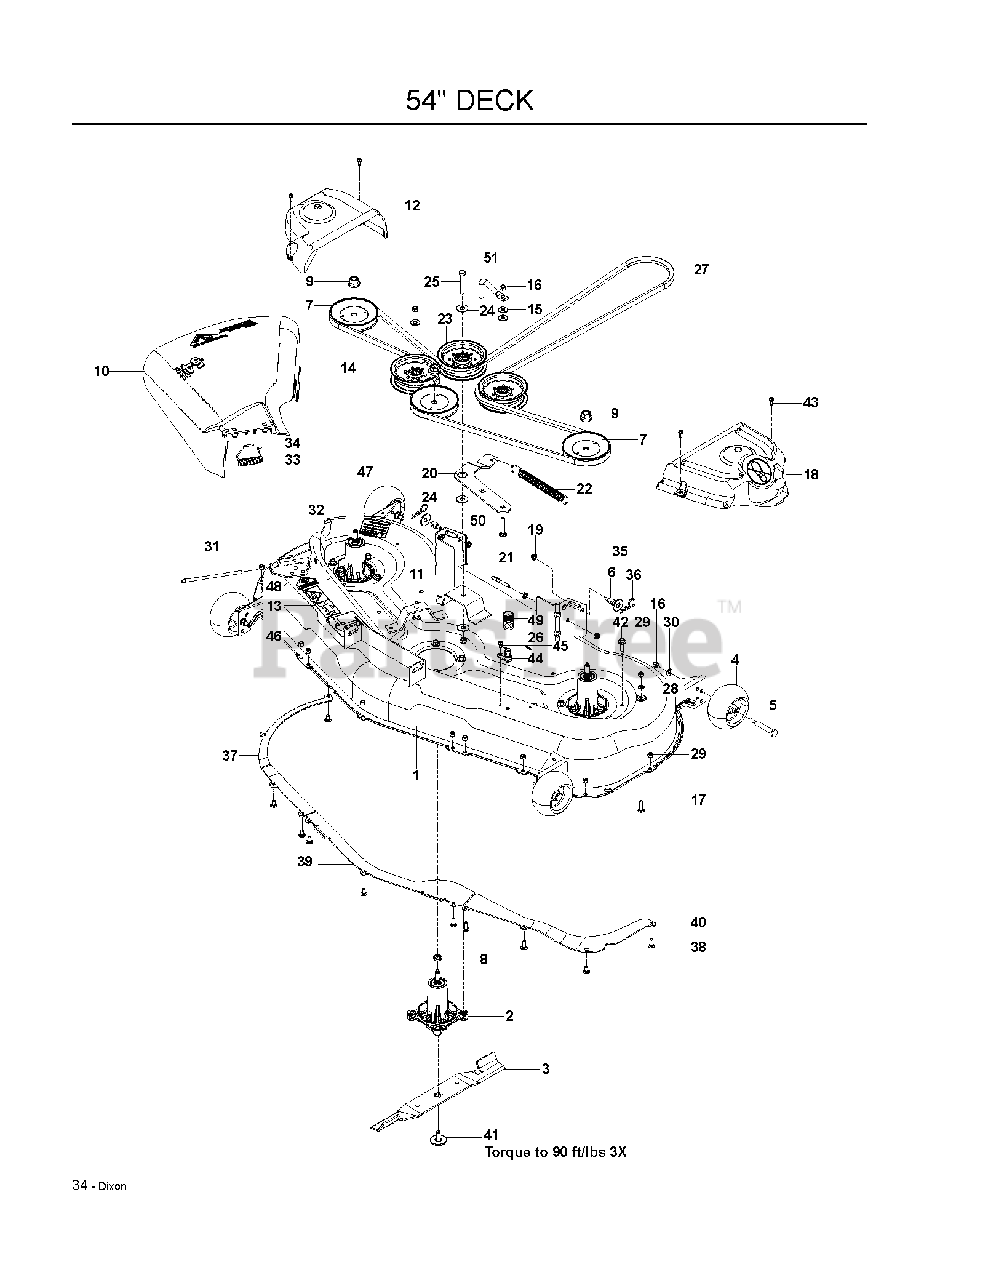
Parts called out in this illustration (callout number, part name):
1	DECK.STAMPED.54".W/DECALS.BLUE
2	MANDREL GREASABLE
3	BLADE, BAGGING 54"
4	GAUGE WHEEL
5	SHOULDER BOLT 1/2X2-5/8 ZD SPE
6	STUD.FASTNER.W/ANTI-ROTATE
7	PULLEY
9	LOCKNUT - 9/16
10	DEFLECTOR, 54"
11	RHSNB 3/8C X 2
12	BELT SHIELD, RT
13	DECAL, EURO SEVERING
14	PULLEY.IDLER.2006
15	WASHER 3/8 FLAT
16	NUT 3/8-16 NYLOC
17	BOLT 5/16C X 3/4" CARRIAGE
18	BELT SHIELD, LT
19	5/16-18 NYLOC FLANGE NUT
20	ARM.IDLER.BLACK
21	EYEBOLT, RH
22	SPRING, DECK BELT
23	PULLEY.IDLER.MWR.STATIONARY.LH
24	WASHER 7/16 FLAT ZD
25	BOLT 7/16-14 X 2-1/2 GR 5 ZD
26	7/16-14 HEX NUT W/NYL RING ZD
27	BELT-DECK, 52
28	FLAT WASHER 5/16 SAE
29	NUT 5/16 NYLOC
30	WASHER 3/8 SAE FLAT
31	ROD, HINGE
32	PUSH NUT
33	TORSION SPRING
34	CAP-SLEEVE
35	WASH USS FLAT 1/2
36	HAIRPIN #4
37	BAFFLE, RIGHT 54"
38	BAFFLE LEFT 54
39	BAFFLE, CENTER, 54"
40	CARRIAGE BOLT 5/16C X 5/8"
41	BLADE BOLT ASSY-7/16" TB REPL
42	WASHER HEAD SCREW
43	SCREW- 1/4-20 X 5/8
44	PORT.WASHOUT
45	BOLT 1/4-20 X 1/2 HWST
46	DECAL, BELT ROUTING
47	DECAL, CAUTION
48	DECAL, CPSC
49	COUPLING.QUICK CONNECT
50	CARRIAGE BOLT 3/8-16 X
51	BELT KEEPER 5"
